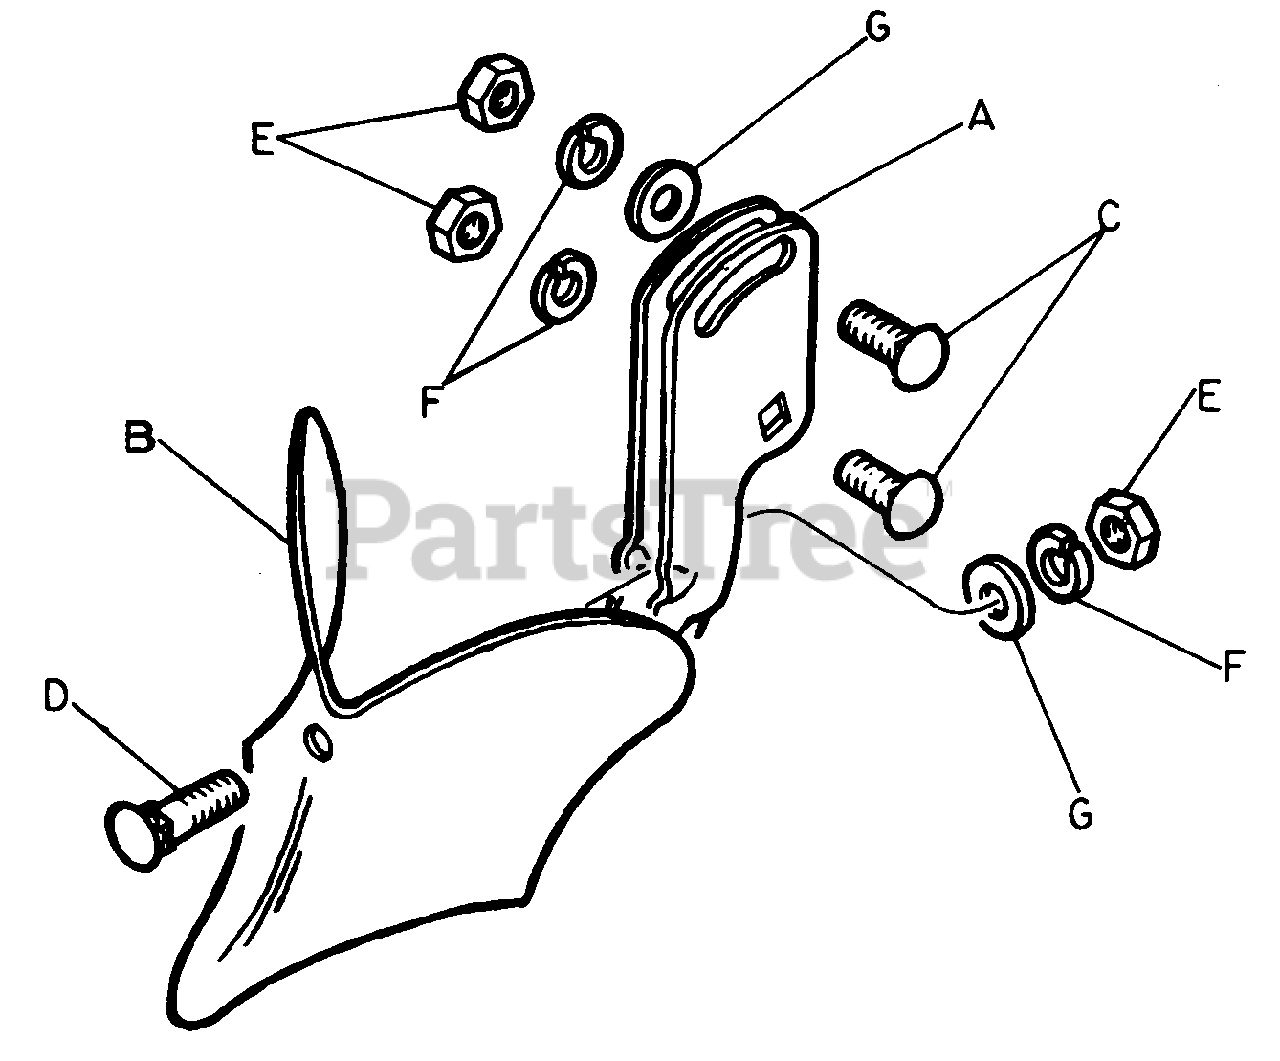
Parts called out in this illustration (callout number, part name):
A	Holder Assembly
B	Shovel
C	Bolt, Carriage, 3/8-16 Plated
D	Bolt, Plow, 3/8-16 x 2 Plated
E	Nut, Hex, 3/8-16 Plated
F	Washer, Lock, 3/8 Plated
G	Washer, Flat, 3/8 Plated
